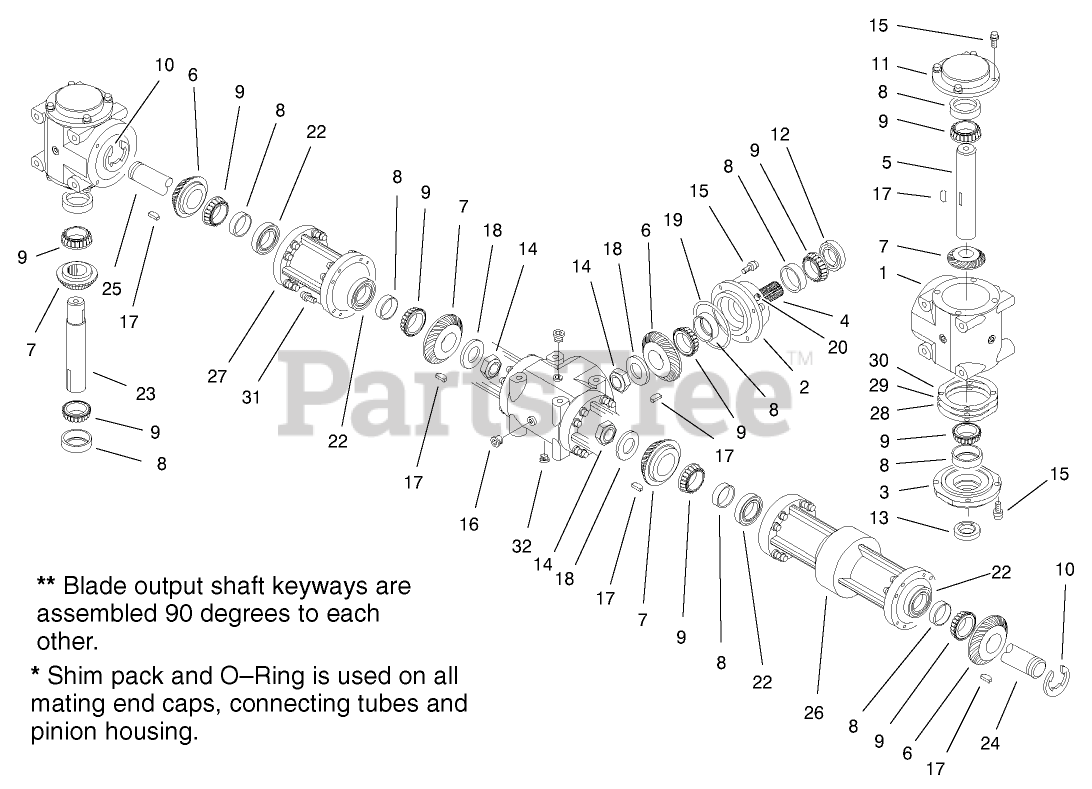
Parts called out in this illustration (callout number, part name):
2	HOUSING - PINION
3	CAP-END, OPEN
4	SPLINED PINION ASM
4	SHAFT - INPUT, SPLINED
5	LH SHAFT ASM
5	SHAFT - CROSS, A/D
6	GEAR - 27 TOOTH
7	GEAR - 29 TOOTH
8	Bearing-Cup
9	Bearing-Cone
10	CLIP-RETAINING
11	CAP-END, CLOSED
13	SEAL
14	NUT-JAM
17	KEY-WOODRUFF
18	WASHER
19	O-RING
21	Cover-Transparent
23	SHAFT - CROSS, B/D
23	Shaft Service ASM, RH
24	SHAFT - CONNECTING, LONG
25	SHAFT - CONNECTING, SHORT
26	FLANGE - CONNECTING, LONG
27	FLANGE - CONNECTING, SHORT
28	SHIM-BROWN, .010IN
29	SHIM-BLUE, .005IN
30	SHIM-GREEN, .003IN
32	PLUG-MAGNETIC
